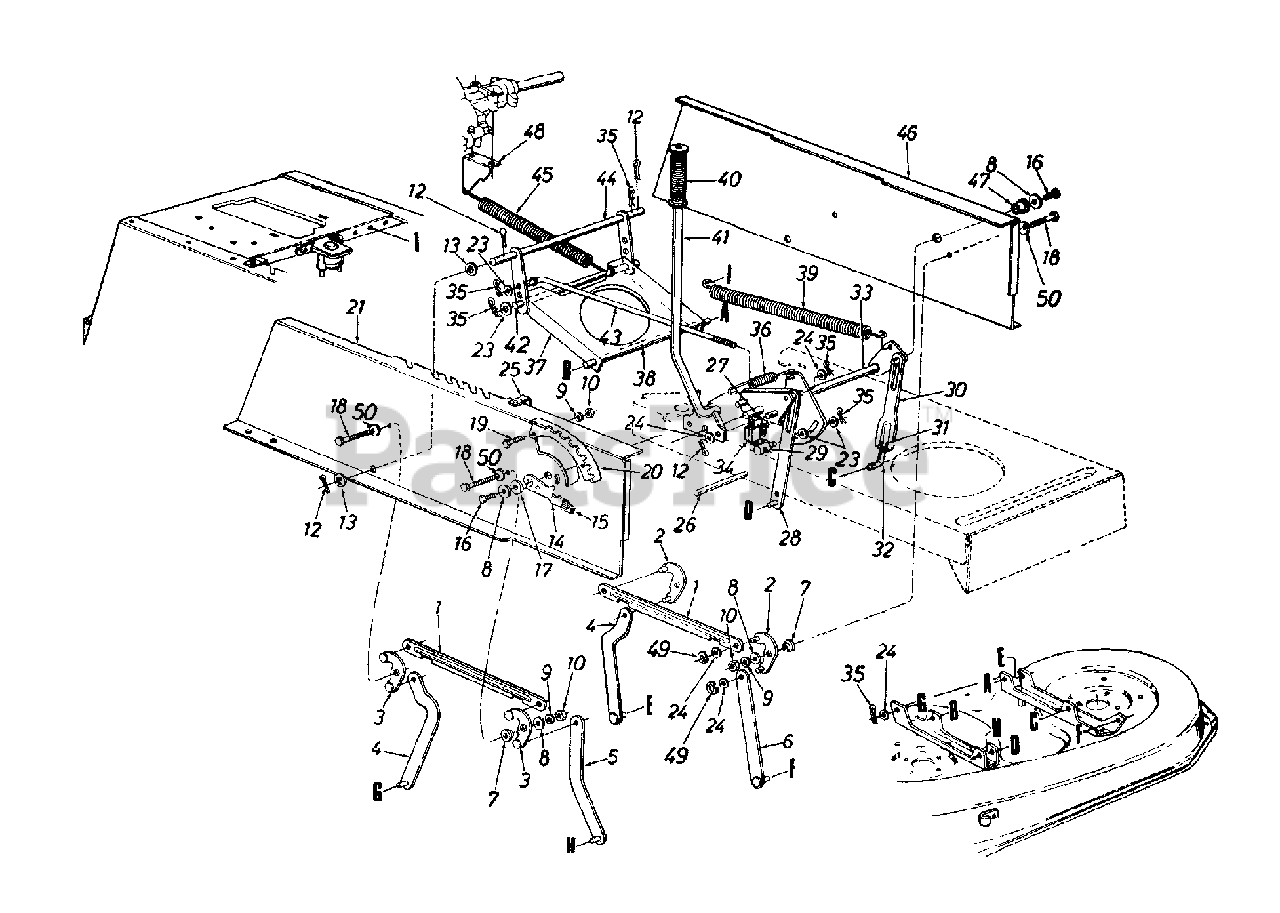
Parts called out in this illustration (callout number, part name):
3	Pivot Link Ass'y. - R.H.
7	Shld. Spacer .318" I.D.
8	Fl-Wash. .344" I.D. x 1.125" O.D.
9	L-Wash. 5/16" I.D.
10	Flange Lock Nut 5/16-18 Thd. (Gr. 5)
12	Cotter Pin 1/8" Dia.
13	Fl-Wash. .635" I.D. x 1.0" O.D.
14	Hgt Adj. Stop Lever Ass'y.
15	Knob
16	Hex Wash. TT-Tap Scr.5/16-18 x .75"
17	Flange Brg. .63" I.D.
18	Hex Wash. Hd. Scr. 5/16-18 x .875" Lg.
19	Hex Bolt 5/16-18 x .75" Lg.
20	Index Brkt.
24	Fl-Wash. .531" I.D. x .93" O.D.
25	Clamp
26	Running Board Rod
27	Hex Wash. Hd. Tap Scr.
31	Hex Nut 1/2-20 Thd. (Gr. 5)
32	Lift Link Adjuster
35	Inter. Cotter Pin 3/8" Dia.
36	Extension Spring
39	Extension Spring
40	Grip (Lift Handle)
43	Disengagement Rod
49	"E"-Ring
50	Bell-Wash. .325" I.D.
